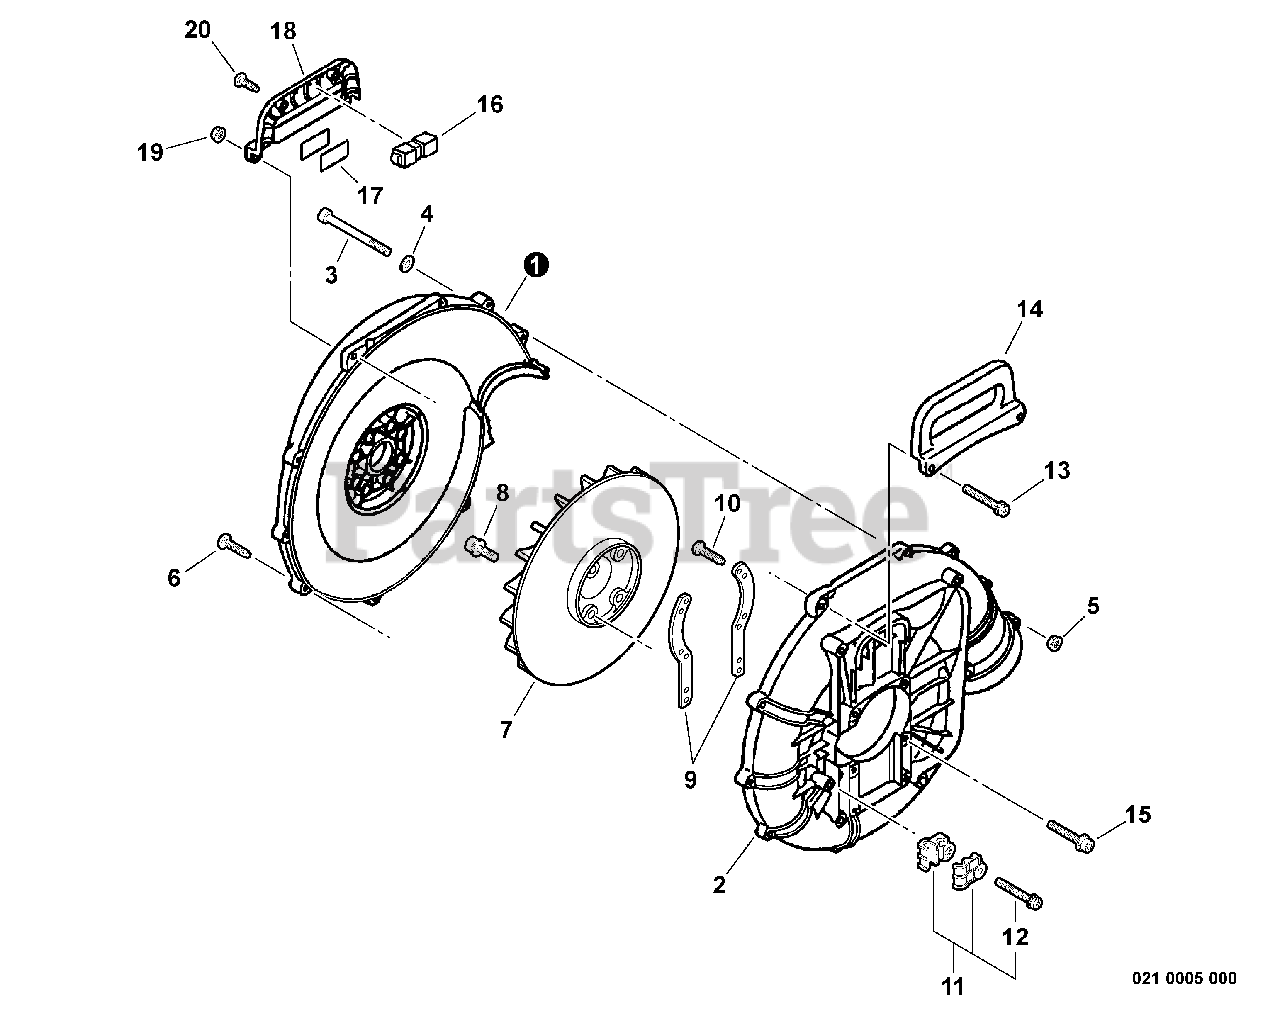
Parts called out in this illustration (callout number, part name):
1	COVER, FAN - INNER -- GRAY
1	COVER, FAN - INNER -- ORANGE
2	COVER, FAN - OUTER -- GRAY
2	COVER, FAN - OUTER -- ORANGE
3	SCREW - 5X60
4	WASHER - 5
5	NUT - 5 -- FLANGE
6	SCREW - 5X30
7	FAN
8	SCREW - 5X20
9	BRACKET, ENGINE
10	SCREW - 3X12 -- TAPPING
11	CABLE HOLDER KIT
12	SCREW - 5X25
13	SCREW - 5X45
14	HANDLE - INNER -- GRAY
14	HANDLE - INNER -- BLACK
15	SCREW - 5X32
16	WEIGHT, HANDLE
18	HANDLE - OUTER -- GRAY
18	HANDLE - OUTER -- BLACK
19	NUT - 5 -- FLANGE
20	SCREW - 5X16 -- TAPPING
